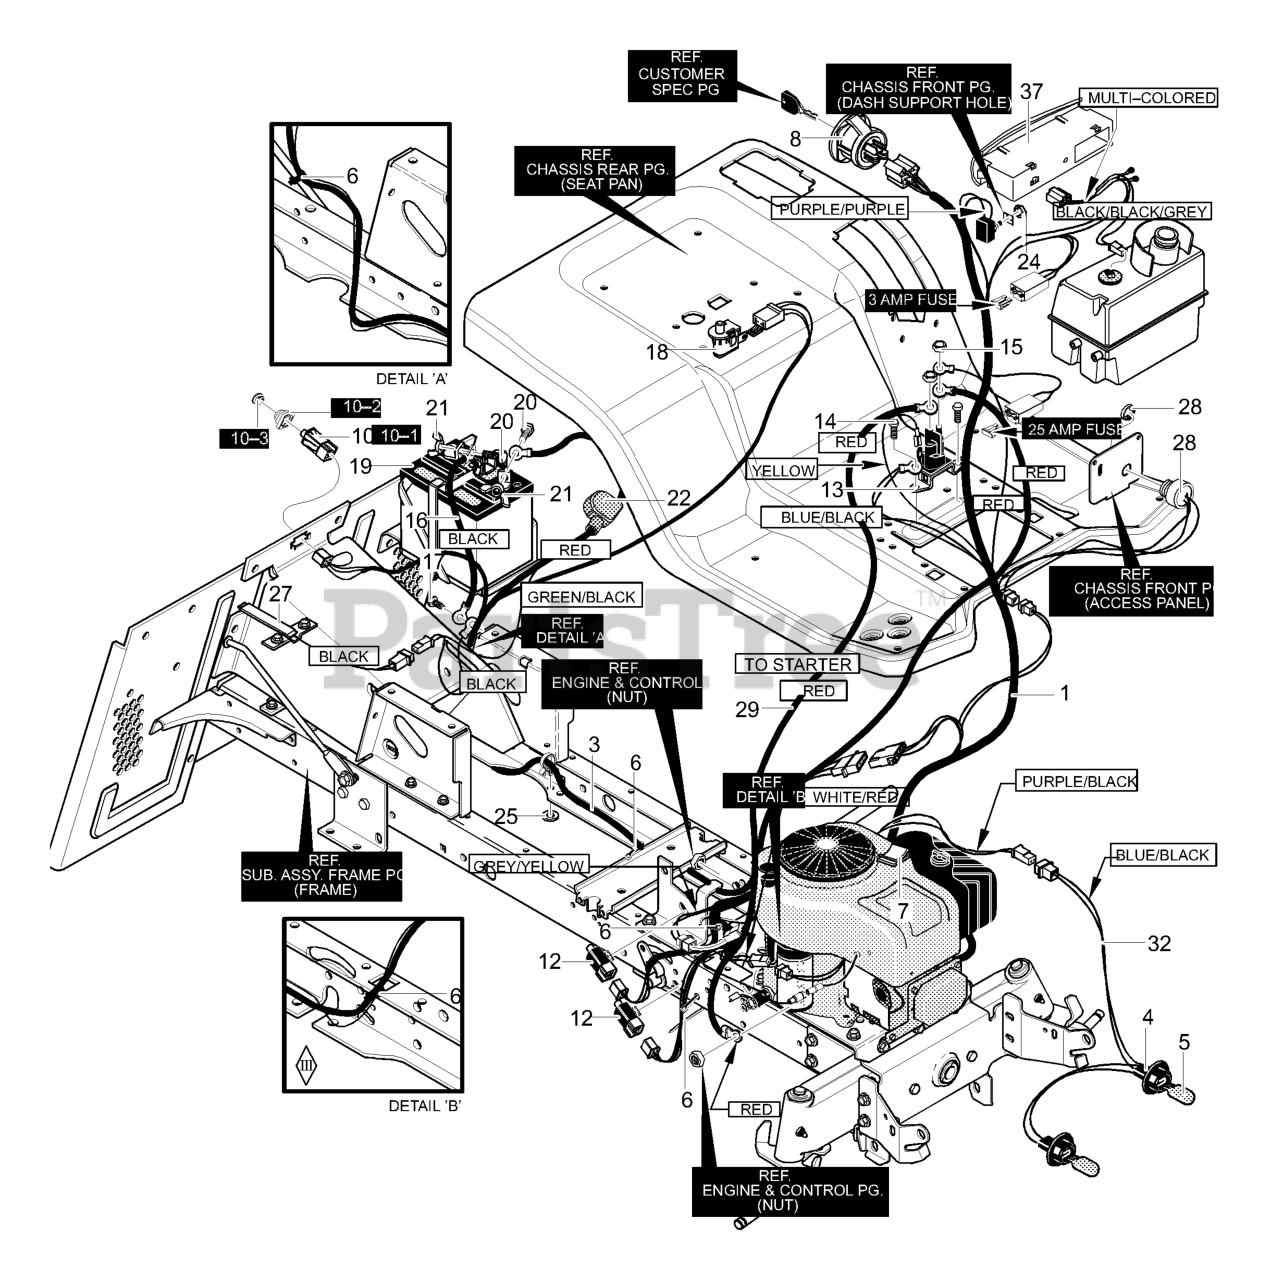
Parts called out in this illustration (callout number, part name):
1	Wire Harness
3	Rear Harness
4	Socket, Lamp
5	Bulb, Light
6	Cable Tie
7	Wire Clip, Adhesive
8	Switch, Ignition
10	ASSEMBLY, Switch Double Pole Delta
10-1	Switch, Double
10-2	Boot, Switch
10-3	Switch Cap
12	Switch, Limit
13	Solenoid
14	SCREW 1/4x.50
15	NUT, 1/4-20
16	Ground Wire
17	SCREW, 1/4x.50
18	Seat Switch
19	Battery 5 Plate
20	BOLT, 1/4-20x.63
21	Wing Nut
22	Boot, Battery
24	NUT, Plastic
25	WASHER, Flat
27	Tape Switch
28	Buzzer, For Bag Full
29	Wire, Lead Solenoid to Starter
32	Wire Harness Headlights
37	Elect. Diagnostic
